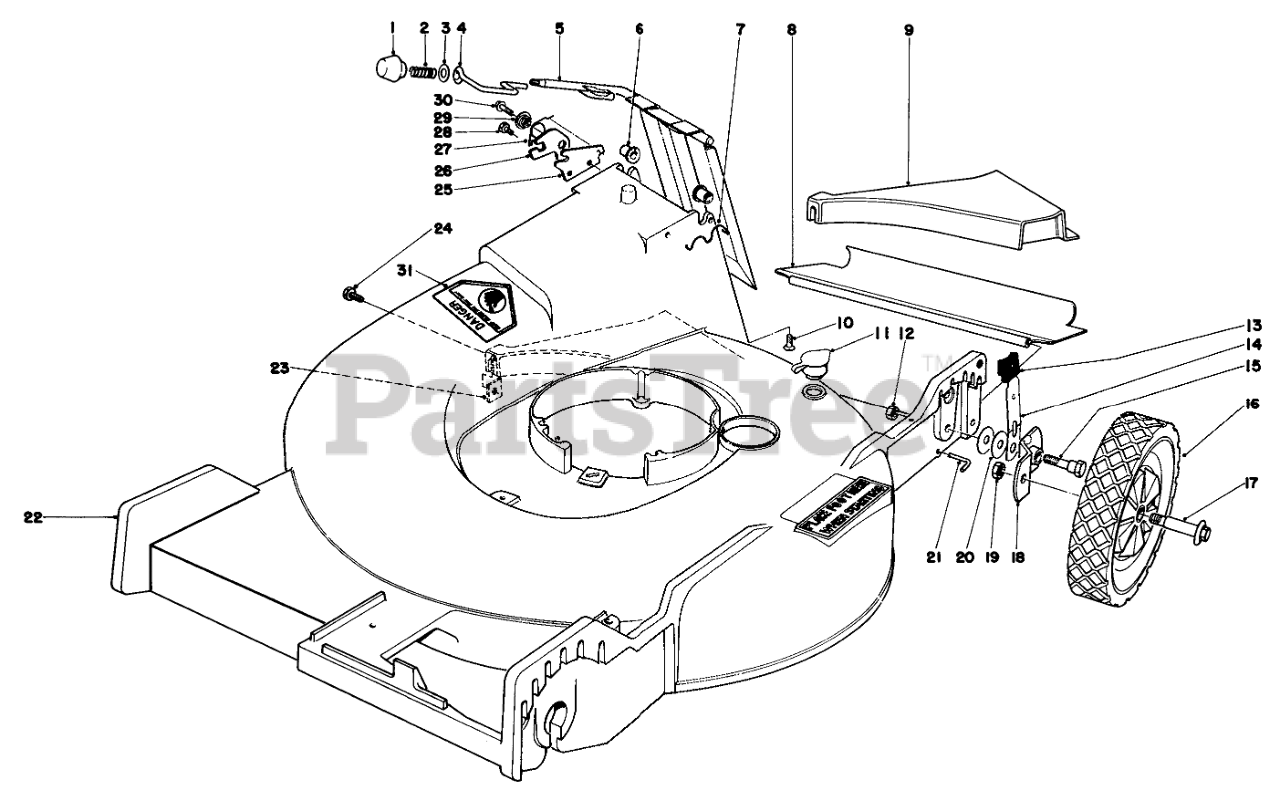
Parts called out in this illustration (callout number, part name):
2	COMPRESSION SPRING
3	WASHER
4	DOOR LATCH
5	Door Handle
6	BUSHING-NYLON
7	Door Retainer
8	REAR SAFETY SHIELD
9	REAR INSERT
10	Flat Hd. Screw
11	WASHOUT PLUG
12	Nut
13	KNOB-ARM
14	SPRING ARM ASM
15	PIVOT SCREW
16	WHEEL TIRE ASM 8 IN
17	BOLT-WHEEL
18	PIVOT ARM ASM A
19	Nut
20	WASHER-PIVOT
21	ROD-SHIELD
22	Housing
23	SPECIAL NUT
24	SCREW THD 1/4 20 5/8
25	DOOR LATCH PLATE
26	Latch Safety
27	TORSION SPRING
28	SCREW-HWH
29	Latch Spacer
30	Screw
31	DECAL-DANGER
